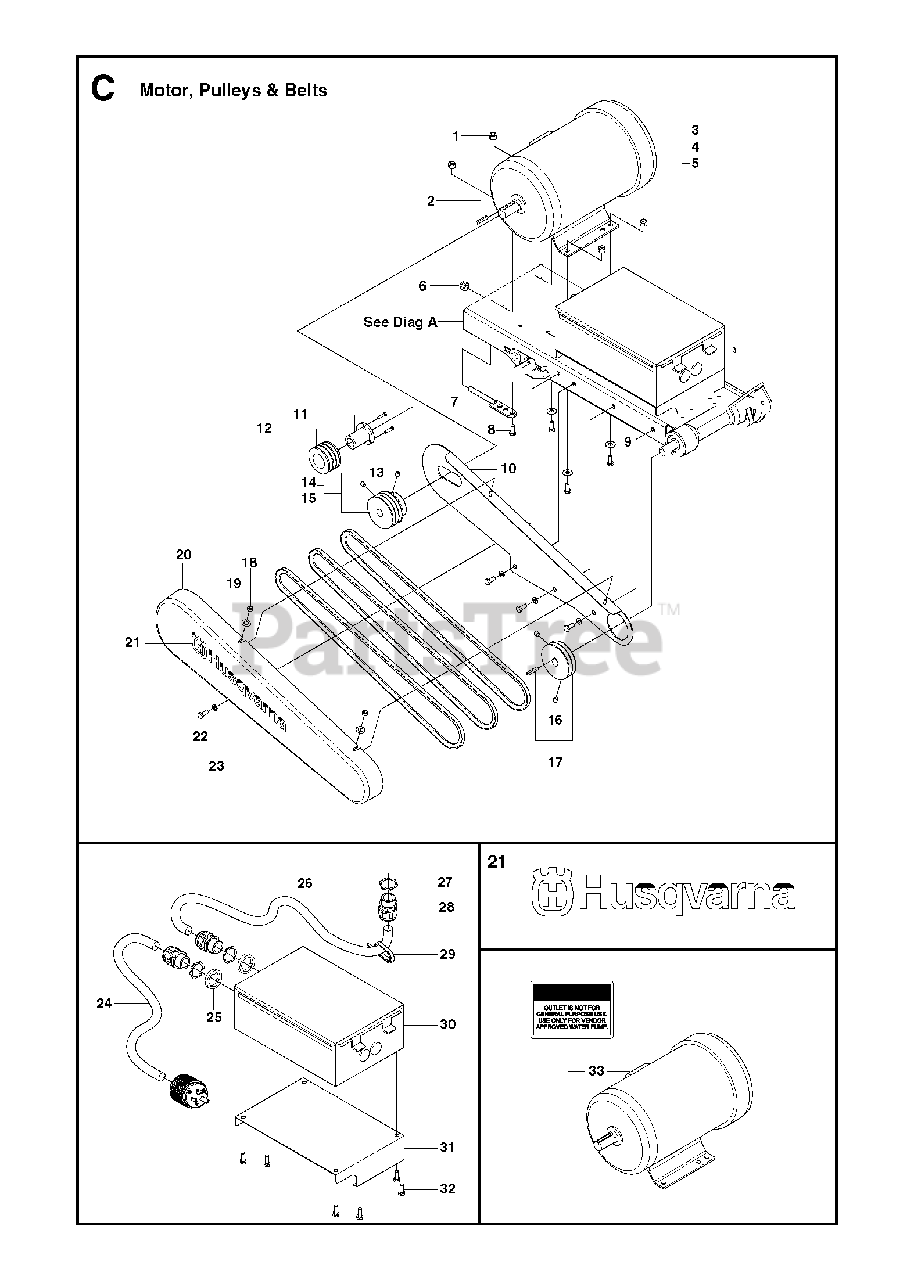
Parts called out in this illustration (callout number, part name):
1	NUT
6	NUT
18	NUT
22	SCREW
23	WASHER
